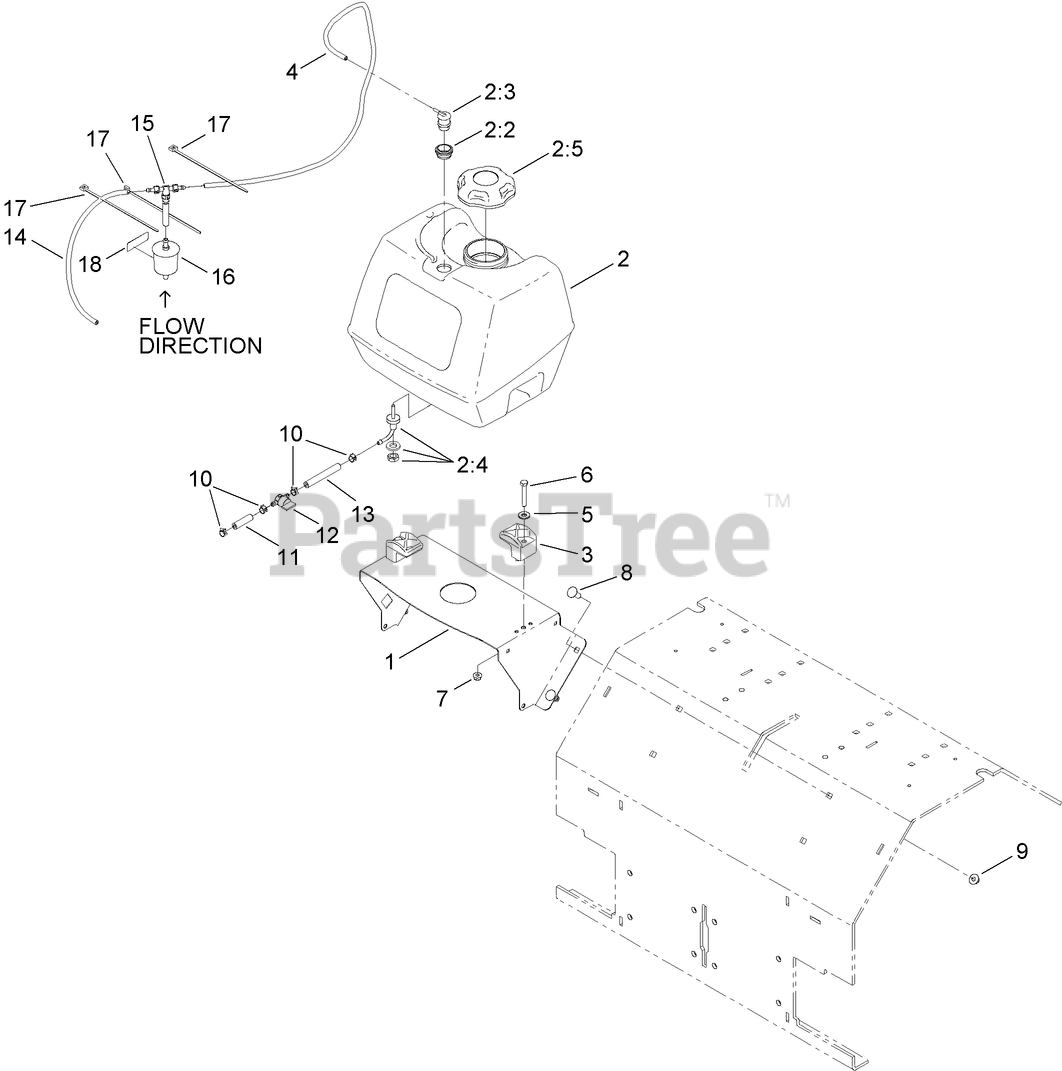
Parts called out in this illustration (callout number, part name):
1	SUPPORT-TANK, FUEL
2	FUEL TANK ASM
2:2	GROMMET
2:3	VALVE-ROLLOVER
2:4	FITTING-FUEL, BULKHEAD
2:5	CAP-FUEL, RATCHETING
4	HOSE-EMISSIONS
5	WASHER-FLAT
6	SCREW-HH
7	NUT-HF, NI
8	BOLT-CARR
9	NUT-HF, NI
10	CLAMP-HOSE
11	HOSE-FUEL
12	VALVE-FUEL
13	HOSE-FUEL
14	HOSE-FUEL
15	TEE AND CHECK
16	FILTER-FUEL
17	TIE-PLASTIC
18	DECAL-FILTER, EMISSIONS
